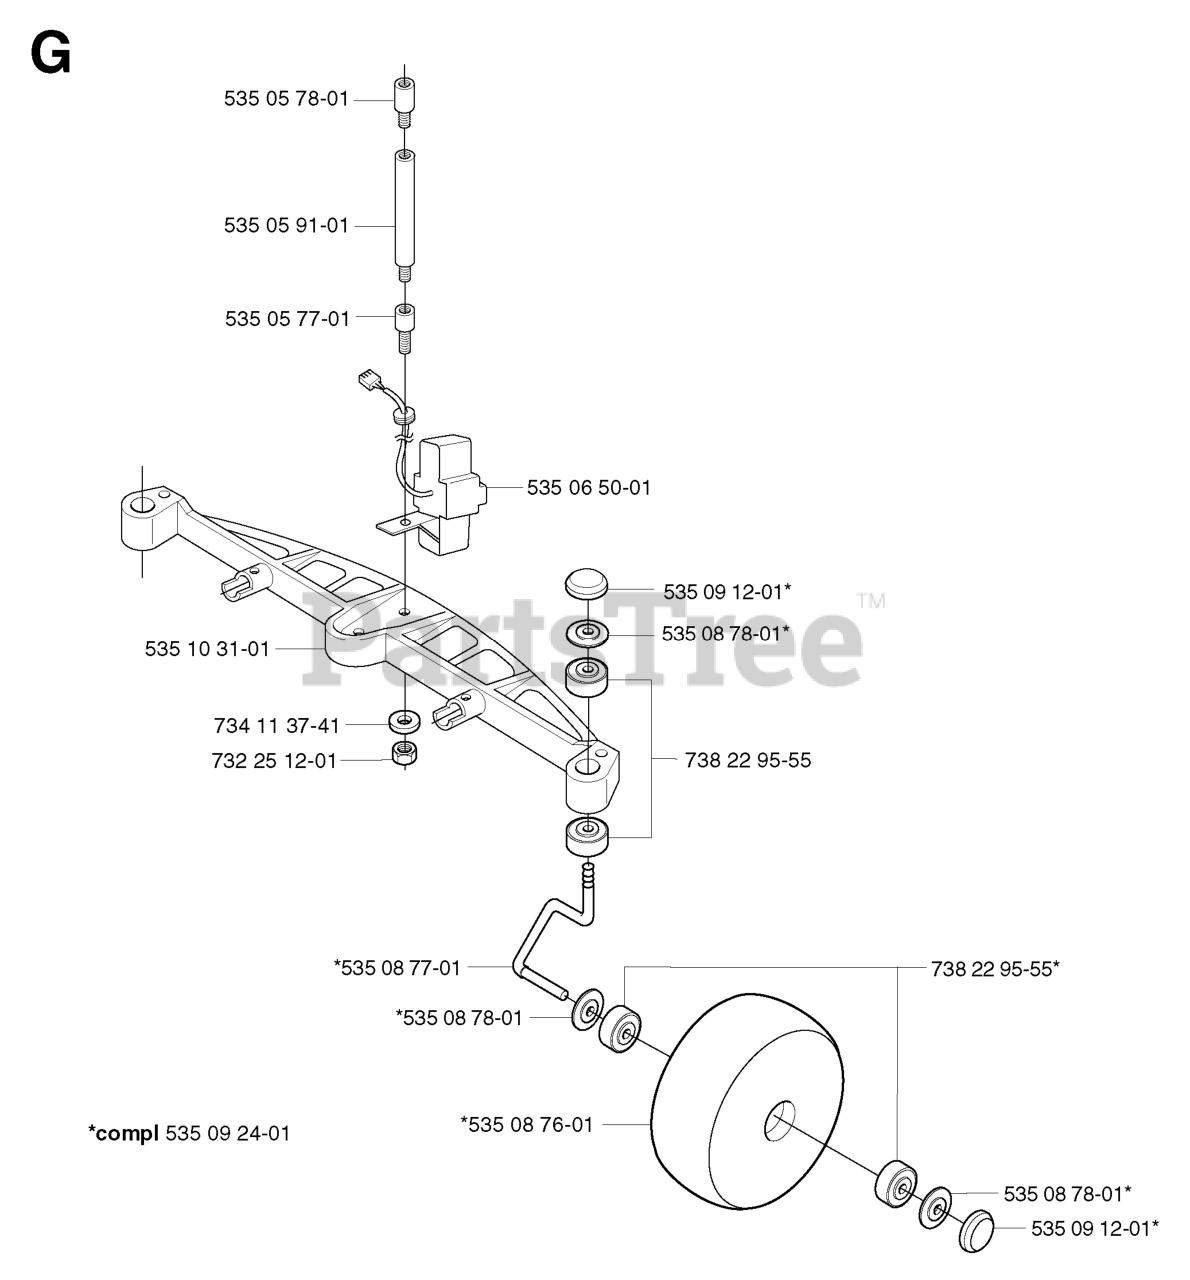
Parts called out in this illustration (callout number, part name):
2	VALVE STEM LT
3	RIM ASSEMBLY, FRONT
4	TUBE.16X6.5/7.5-8
5	TIRE HEAVY DUTY
6	FITTING LT
7	BEARING T
8	CAP, AXLE BLK
9	TIRE HEAVY DUTY
10	TUBE.23X9.5-12
11	RIM.ASM.12X7.REAR.SILVER
12	ZERK FITTING M
